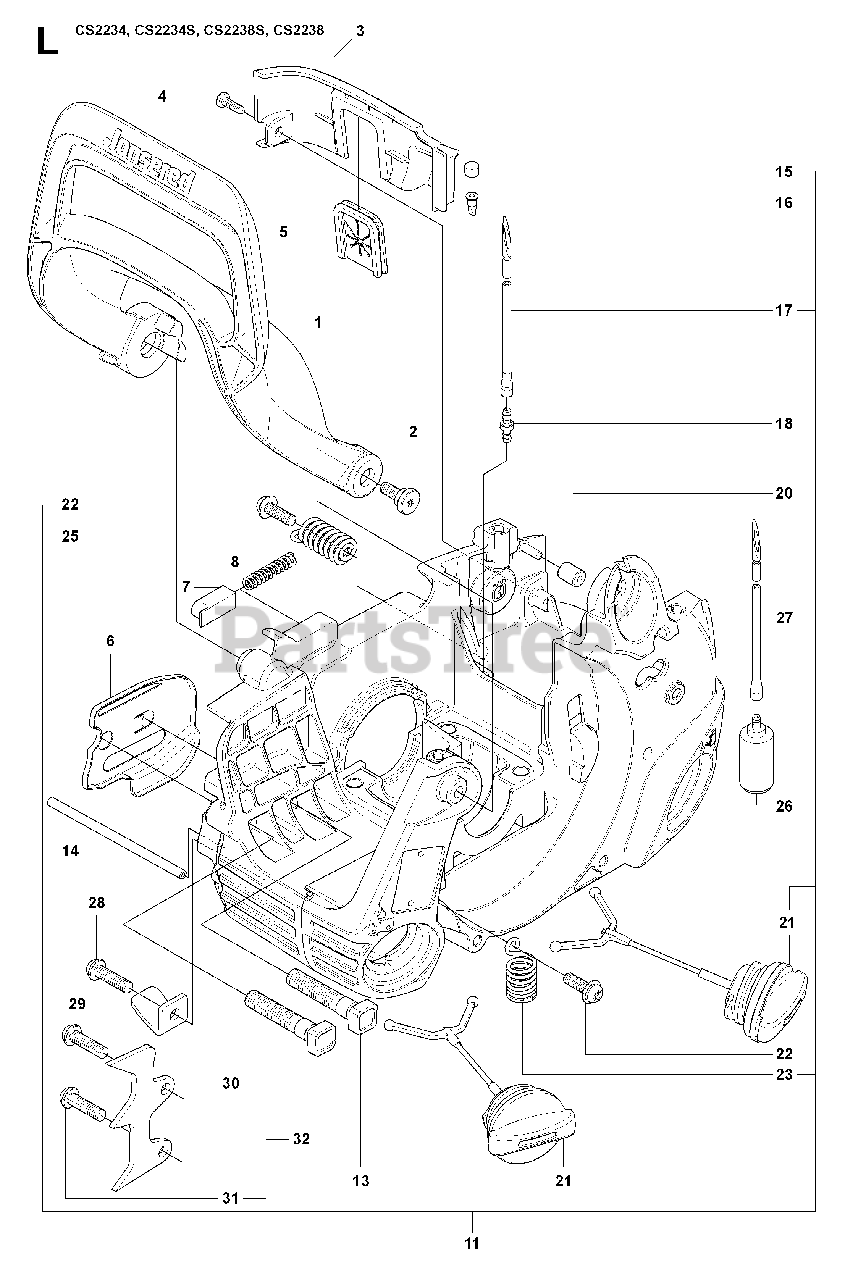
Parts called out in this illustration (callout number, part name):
1	HAND GUARD
2	BOSS SCREW
6	PLATE BAR
7	CAP, SPRING HANDGUARD
13	BOLT
14	OIL TUBE
15	VENT,FUEL TANK 36/41
16	VALVE-CHECK (DUCKBILL)
17	LINE KIT
18	FUEL LINE FITTING
20	ISOLATOR FILTER HOUSING
21	ASSY CAP FUEL/OIL
22	SCREW,FRONT HBAR 36/41
23	ISOLATOR
25	SPRING
26	FUEL PICK-UP ASSY
27	FUEL LINE
29	CHAIN CATCHER 36/41
30	SPIKE
31	SCREW
32	SPIKE 36/41
